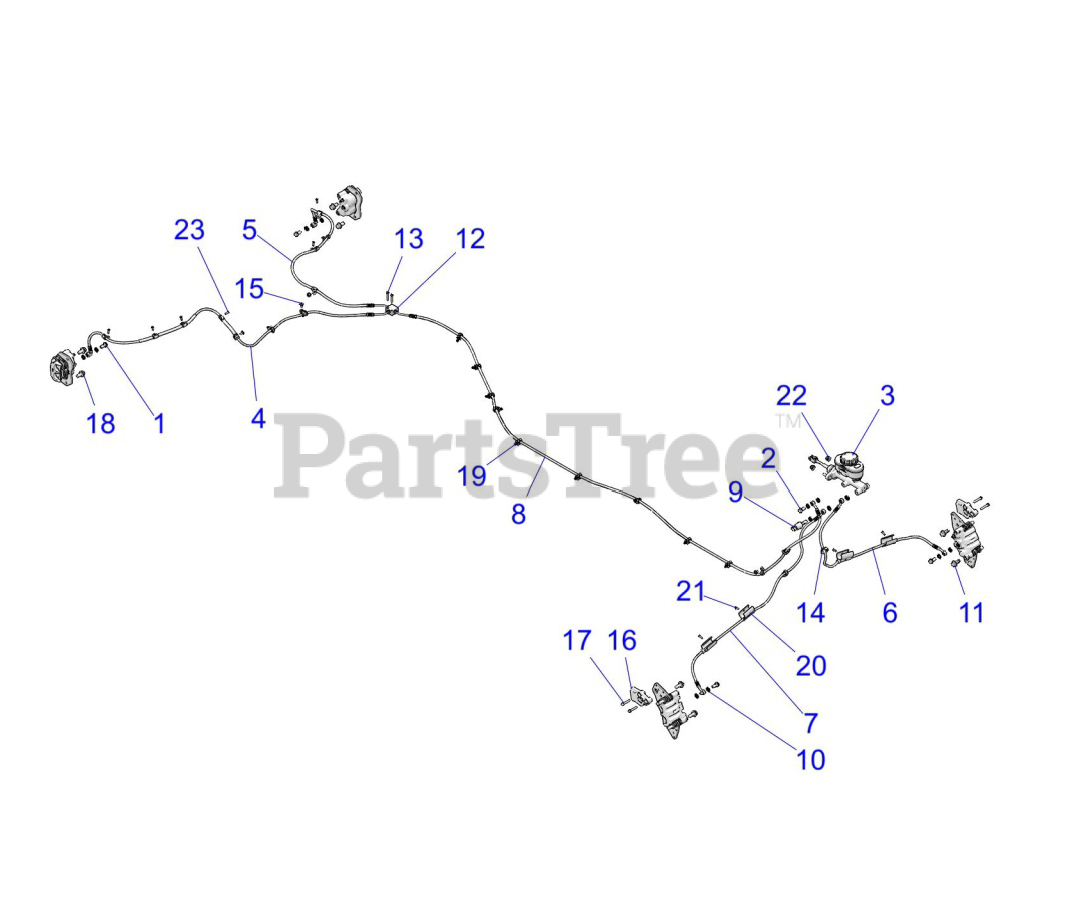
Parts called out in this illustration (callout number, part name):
1	BOLT-BANJO,10MMX1.00
2	BOLT-BANJO, 10MM X 1.25-6G
3	ASM-M/C-T-FLANGE,3/4 BORE
4	LINE-BRK,RR,J
5	LINE-BRK,RL,41.1,45F,90SB,290J
8	LINE-BRK,M/T,72.7,20B,20F,263
9	SWITCH-BRK,M10X1.25,DBL,SEALED
10	SEAL-STAT-O-3/8,70EP
11	BOLT-M10X1.25X25,HXFLG,W/PATCH
12	FITTING-TEE,BRAKE
13	SCR-10-24X1.25TFM PN TRX TRI-Y
14	CLIP-ROUTING
15	SCREW(10)
16	SCRAPER-BRAKE,FRONT
17	SCR-HXFL,M6X1.0X35,W/PATCHLOK
18	BOLT-M10X1.25X20,HXFLG-OLV D
19	CLIP-NYLON,C,FIR-TREE
20	RETAINER-BRAKE LINE,1"
21	POP RIVET(50)
22	NUT-M8X1.25,FLG,NYLOC-OLIVE D
